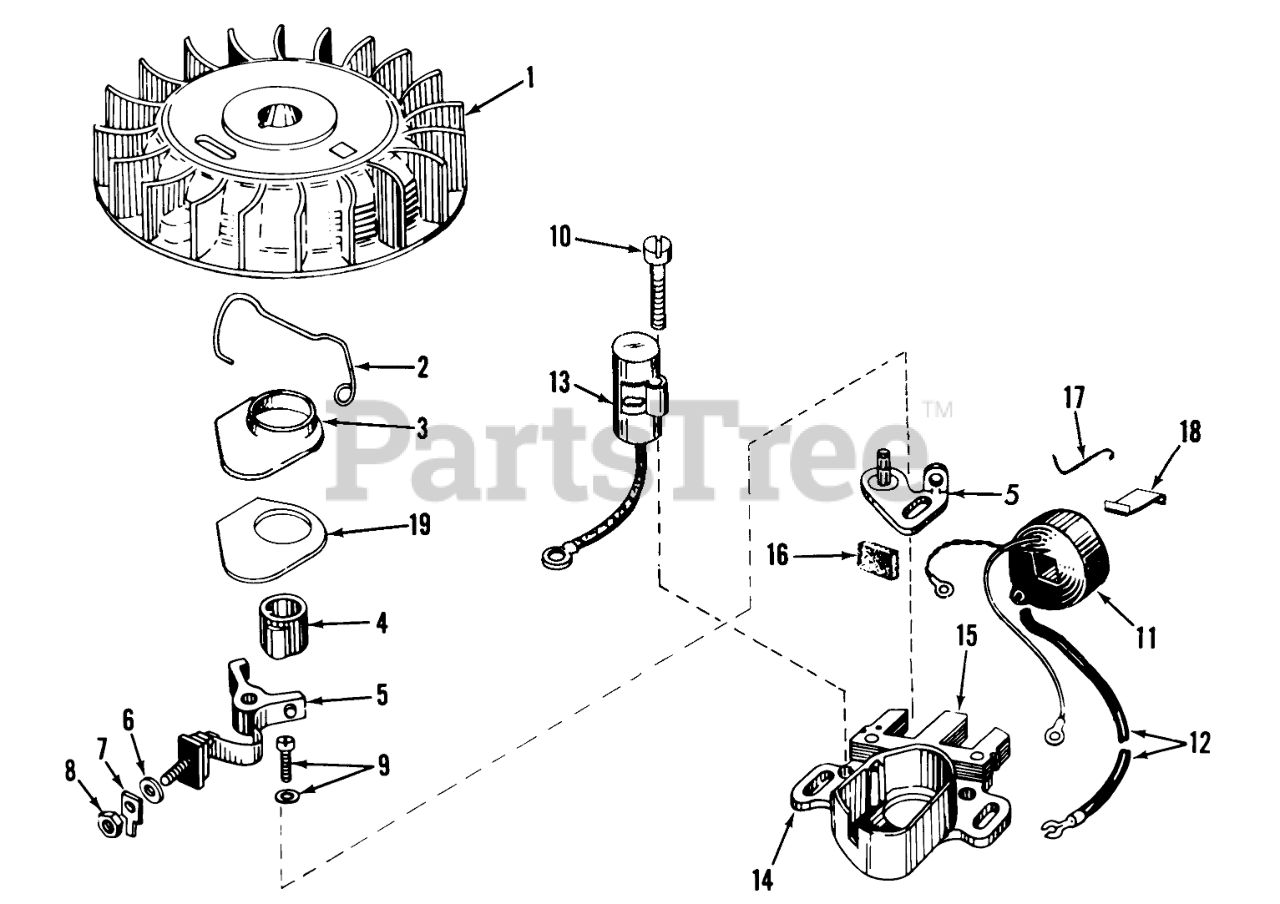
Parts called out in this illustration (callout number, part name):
1	Flywheel
2	Spring Breaker Box
3	Cover, Dust
4	Cam-Breaker
5	Breaker Assy.
7	Terminal
9	Breaker Screw
10	Screw, Condenser Fastening
11	Coil Assy., (Incl. Ref. Nos. 12, 13 & 18)
12	Wire, Lead
13	Condenser
14	Core & Plate
15	Stator Assy., (Incl. Nos. 2, 3, 5 thru 14 & 16 thru 19)
16	Felt,Cam Wiper
17	Clip, Coil
18	Spring Coil Wedge
19	Gasket Dust
